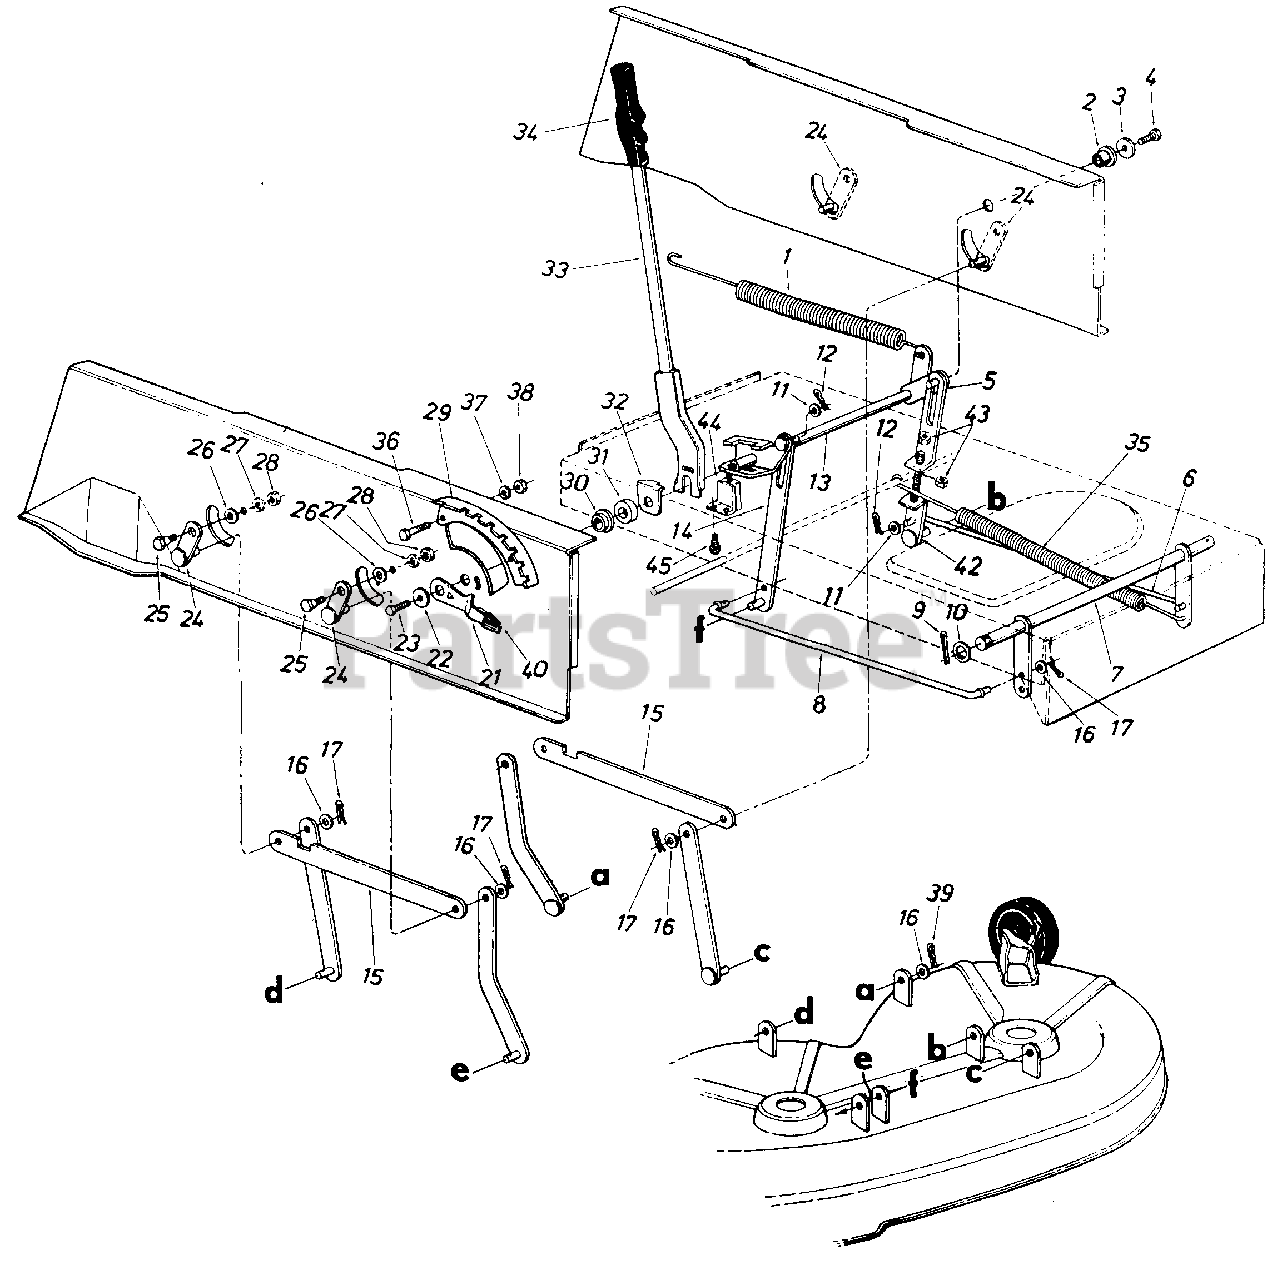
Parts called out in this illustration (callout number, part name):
1	Extension Spring .99" O.D. x 11.00" Lg.
2	Flange Bearing .634" I.D.
3	Fl-Wash. .344" I.D. x 1.125" O.D. x .125
4	Hex Wash. Hd. 5/16-18 x .62" Lg.
5	Adj. Link Lift
6	Stabilizer Rod
7	Stabilizer Shaft Ass'y.
8	Stabilizer Rod
9	Cotter Pi n 118" Dia. x 11/4"
10	Fl-Wash. .635" I.D. x 1.12" O.D.
11	Fl-Wash. .531" I.D. x .940"O.D.
12	Inter. Cotter Pin .50" Dia.
15	Connecting Rod
16	Fl-Wash. .40" I.D. x .88"O.D.
17	Inter. Cotter Pin For 3/8" Rod
21	Deck Lift-Down Stop
22	Fl-Wash. .344" I.D. x 1.125" O.D. x .125
23	Hex Wasn. Hd. Self-Tap Scr. 5/16-18 x .62" Lg.
24	Pivot Link Ass'y.
25	Shld. Bolt .437" Dia. x .180" Lg. (5/16-18)
26	Fl-Wash. .344" I.D. x .62"O.D.
27	L-Wash. 5/16" I.D.
28	Hex Nut 5/16-18 Thd.
29	Index Brkt.
30	Flange Wash. .628" I.D. x 1.25" O.D.
31	Rubber Wash. 1.50" O.D. x .63" I.D. x .60
32	Retainer Washer-Lift Handle
33	Lift Handle Ass'y.
34	Grip
35	Extension Spring .99" O.D. x 13.25" Lg.
36	Hex Bolt 5/16-18 x .75" Lg.*
37	L-Wash. 5/16" I.D.
38	Hex Nut 5/16-18 Thd.
39	Inter. Cotter Pin
40	Knob
42	Adj. Link Lift Ass'y.
43	Hex Jam Nut 3/8-16 Thd.
44	Safety Switch
45	Hex B-Tap Scr. #10 x .50" Lg.
